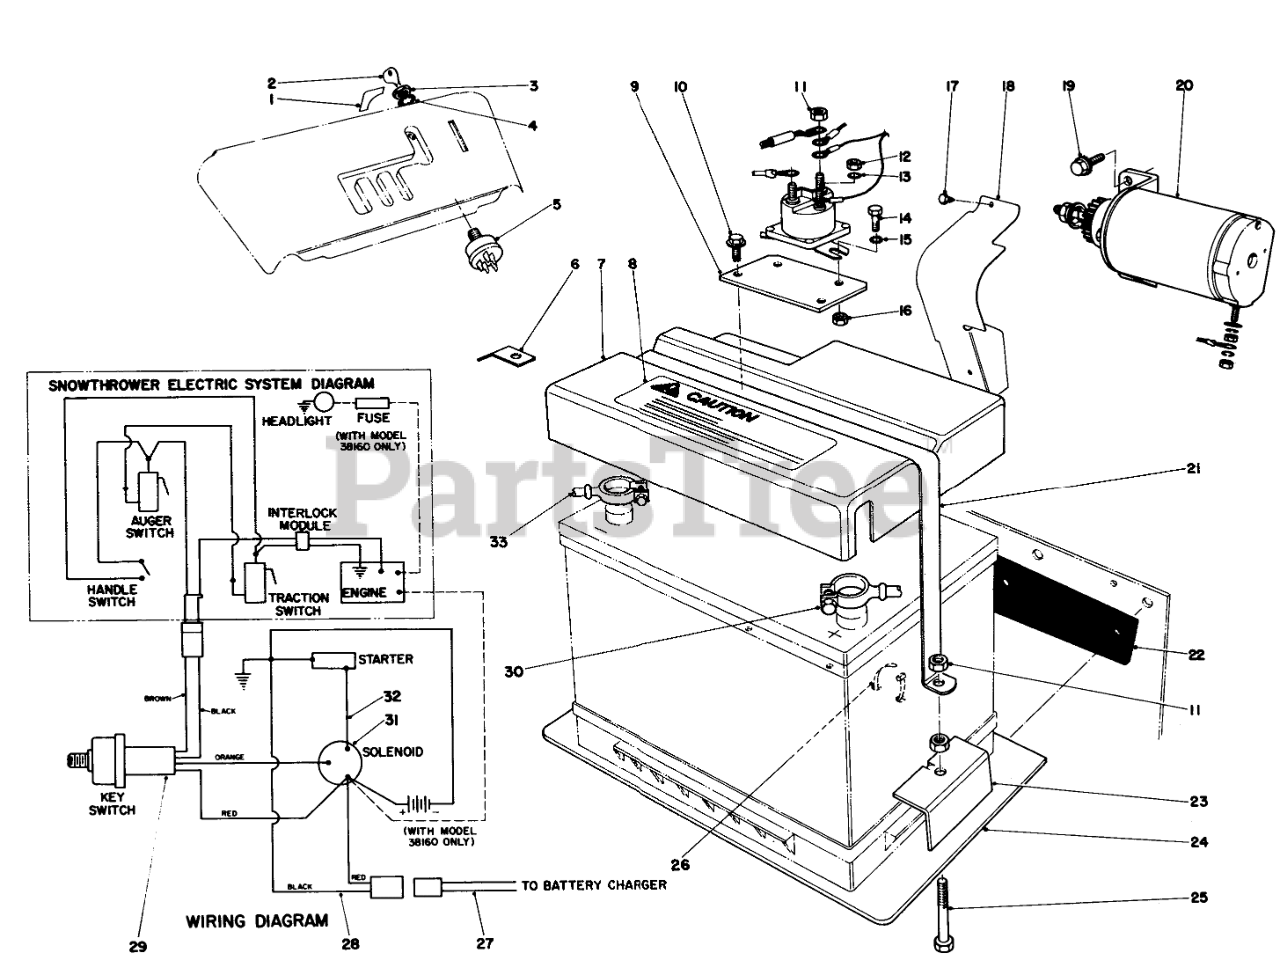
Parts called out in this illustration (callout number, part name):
1	Decal Switch
2	Key
3	NUT-HH
4	WASHER-TOOTH, INTERNAL
5	Smarter Switch
6	Bracken Wire Clamp
7	Battery Cover (Incl. Ref. #8)
8	0630 Decal-Caution
9	Bracket Solenoid
10	SCREW-HWH
11	NUT-HEX
12	NUT-HEX
13	WASHER-LOCK, INT
14	SCREW-HH
15	WASHER-LOCK/EXT
16	NUT-LOCK, NI
17	Hex Hd. Sems Screw
18	Pinion Shield
19	Screw-HH
20	Starter Motor & Pinion Assy.
21	Strap Battery
22	Batery Isolation Pad
23	BATTERY CLAMP
24	Battery Mounting Plate
25	SCREW-HH
26	TIE-CABLE
27	MALE WIRE ASM
28	FEMALE WIRE ASM
29	Wire Harness
30	BATT-SOLENOID CABLE
31	SOLENOID
32	STRT MTR-SOLNOID WIRE
33	BATT-GROUND CABLE
